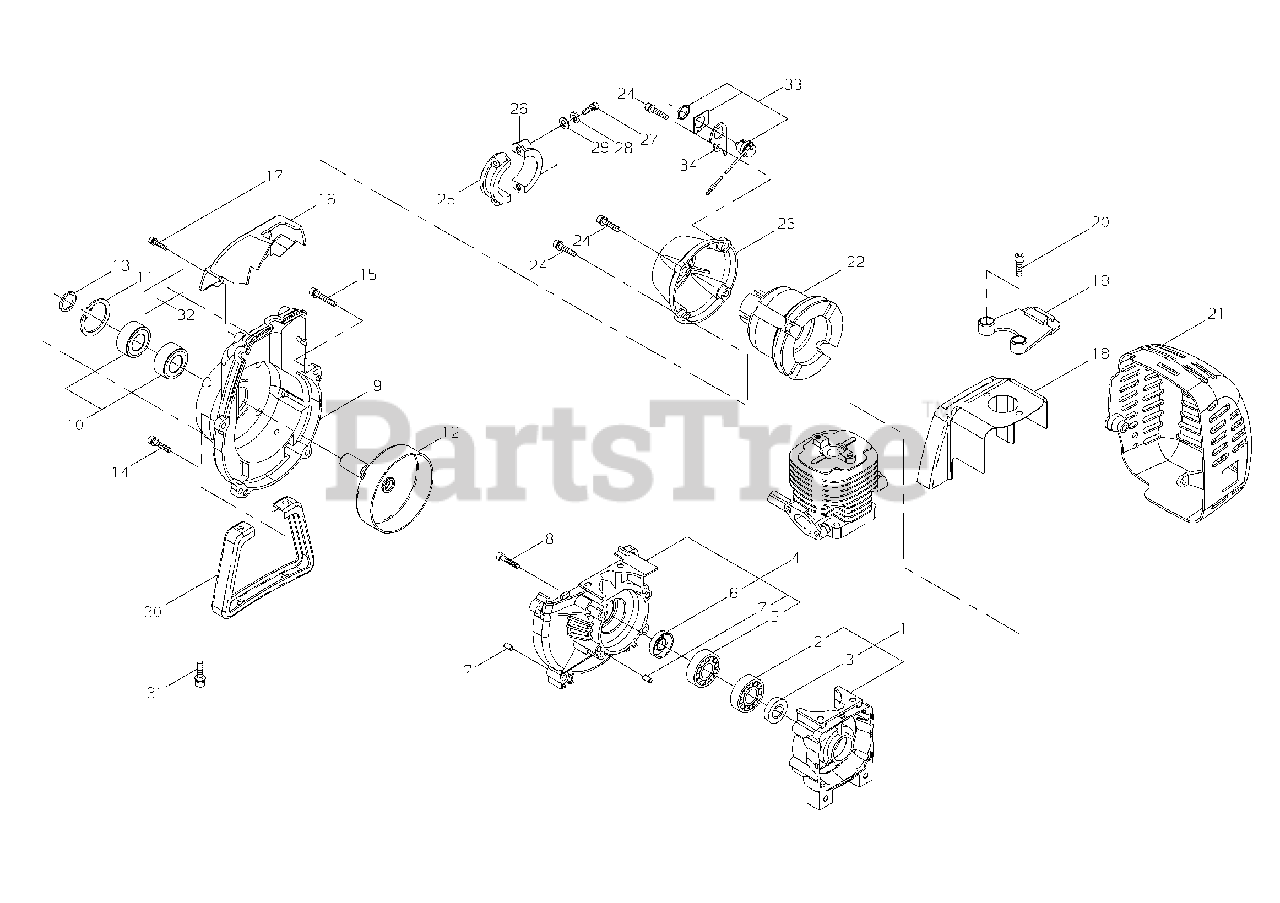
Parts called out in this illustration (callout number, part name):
1	CRANKCASE ASSY, S
2	BEARING, BALL 6202C3
3	SEAL, OIL 16
4	CRANKCASE ASSY, M
5	BEARING, BALL 6202C3
6	SEAL, OIL 16
7	PIN, LOCATING 5×10
8	BOLT 5×30
9	COVER, FAN
10	BEARING, BALL 6002
11	RING, SNAP Ø32
12	DRUM, CLUTCH
13	RING, SNAP
14	BOLT M5×20
15	BOLT M5×30
16	GUARD, TOP
17	BOLT M4×16
18	COVER, ENGINE
19	STAY, ENGINE COVER
20	BOLT M5×18
21	COVER, EXHAUST
22	CUSHION, AV
23	CAP, CUSHION
24	BOLT M5×20
25	CLAMP - A
26	CLAMP - B
27	BOLT 5×25
28	WASHER, SPRING 5
29	WASHER, FLAT 5.5×10×0.8
30	STAND
31	BOLT M5×16
32	LABEL, TRADE
33	SWITCH, ON-OFF
34	BRACKET
